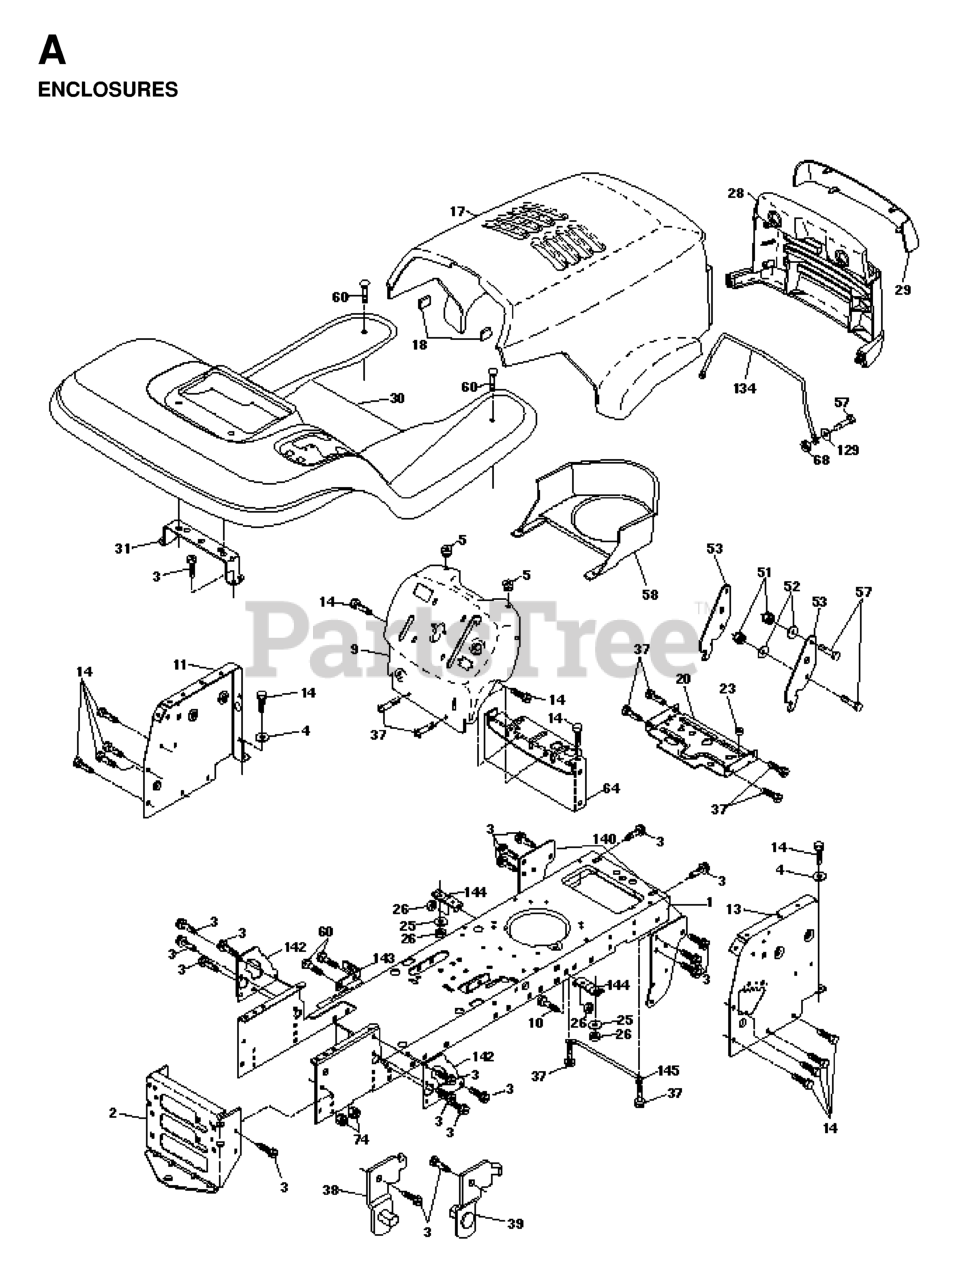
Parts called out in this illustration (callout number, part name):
1	CHASSIS WELDMENT
2	STRETCH DRAWBAR
3	SCREW
4	Washer 13/32 X 3/4 X 16 Ga.
5	BUMPER.RUBBER.HOOD
9	DASH PANEL
10	BOLT D
11	PANEL DASH LH
17	HOOD - LT/YT
18	BUMPER HOOD T
20	PLATE MTG
23	BUSHING.SNAP.NYL.BLK.
25	WASHER
26	NUT
28	GRILLE LT/PL HUSQVARNA
29	LENS LT/PL HUSQVARNA
30	FENDER FOOTREST
31	BRACKET.SUPPORT.FENDER
37	Screw 5/16-18 x 1/2 Hex, Self Tapping 5/16-18 x 1/2
38	BRACKET LH PIVOT
39	BRACKET RH PIVOT
51	LOCKNUT.NYLOC.1/4-20
53	BRACKET PNT PICK OFF LT/PL
57	BOLT
58	AIR DUCT P/L/LT
60	Bolt - Rd. Hd. Sq. Neckiage 3/8 16 x 3/4
64	DASH LOWER
68	NUT
134	ROD SUPPORT HOOD LT/PL HUS.
140	BRACKET SUSPENSION FRONT
142	PLATE REINFORCEMENT
143	BRACKET, SWAY BAR
144	BRACKET FOOTREST
145	ROD PIVOT CHASSIS/HOOD
